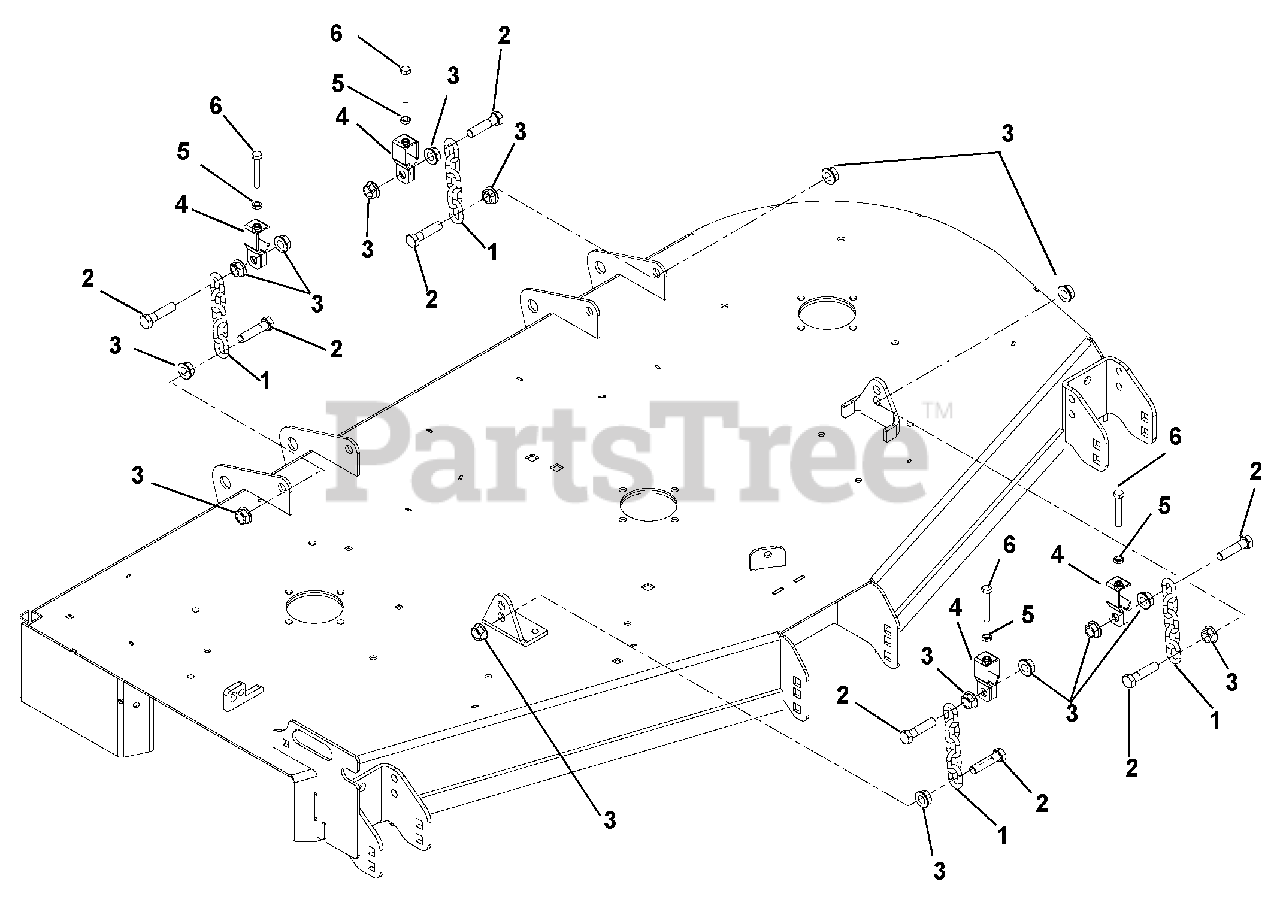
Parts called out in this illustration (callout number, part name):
1	Chain, Link
2	Bolt, Hex M12-1.75 x 50 Class 8.8
3	Nut, Spin Lock Flange M12-1.75
4	Bracket, Deck Leveling
5	Nut, Jam .312-18
6	Bolt, Hex .312-18 x 2.00 FTH Grade 5
